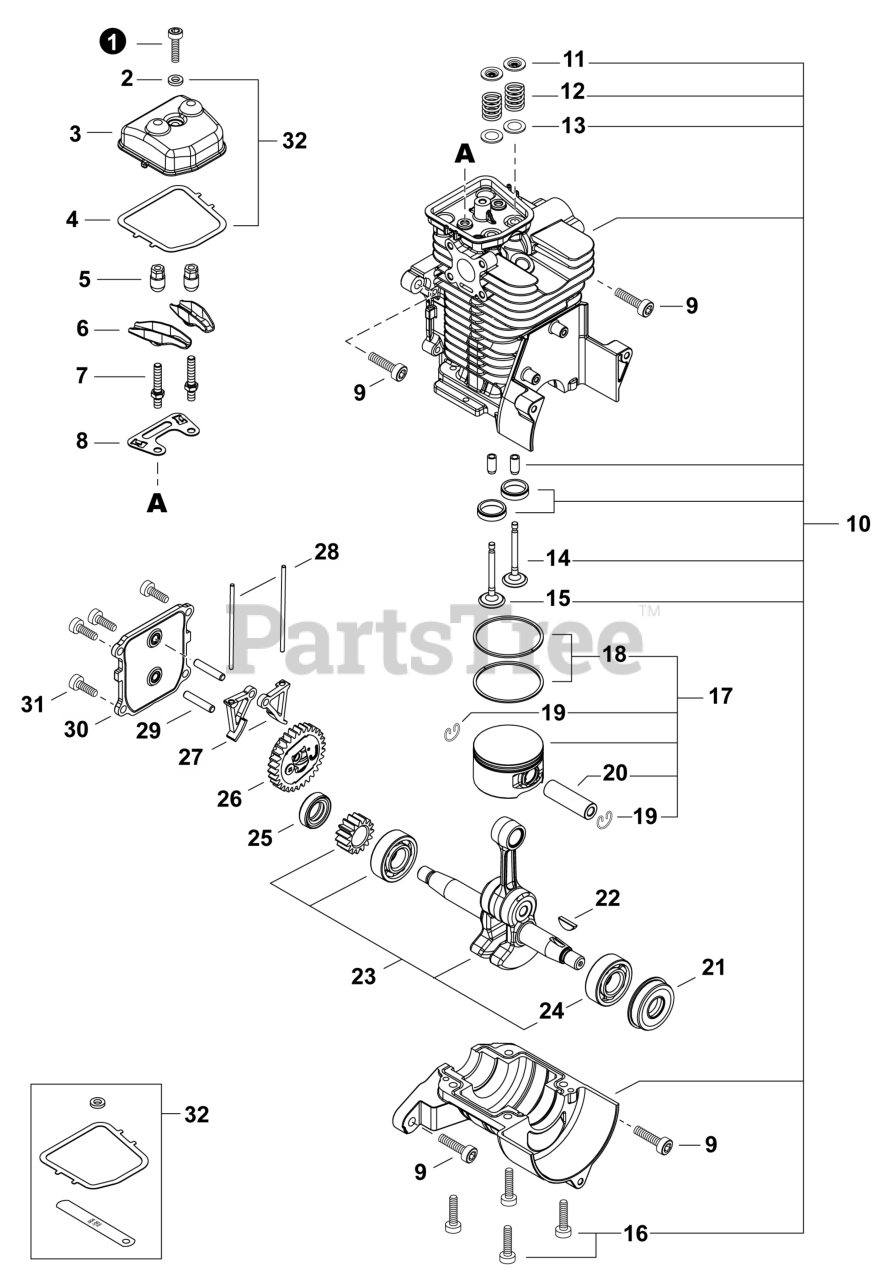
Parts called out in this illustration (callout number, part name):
1	BOLT, TORX 5x20
2	WASHER 10x5.5x2
3	COVER, VALVE
4	GASKET, VALVE COVER
6	ARM, ROCKER
7	BOLT, STUD 5
8	PLATE, GUIDE
9	BOLT, TORX 6x25
10	CYLINDER & CRANKCASE SET
11	RETAINER
12	SPRING, VALVE
13	WASHER 10
14	VALVE, EXHAUST
15	VALVE, INTAKE
16	BOLT, TORX 5x20
17	PISTON KIT
18	RING, PISTON
19	RING, SNAP
20	PIN, PISTON 12
21	SEAL, OIL 15
22	KEY, WOODRUFF 3x14
23	CRANKSHAFT ASSY
24	BEARING, BALL 6202
25	SEAL, OIL 15
26	CAM GEAR ASSY
28	PUSHROD
29	PIN 5x26
30	COVER, CAM GEAR
31	BOLT, TORX 5x16
32	VALVE KIT, ADJUSTING
